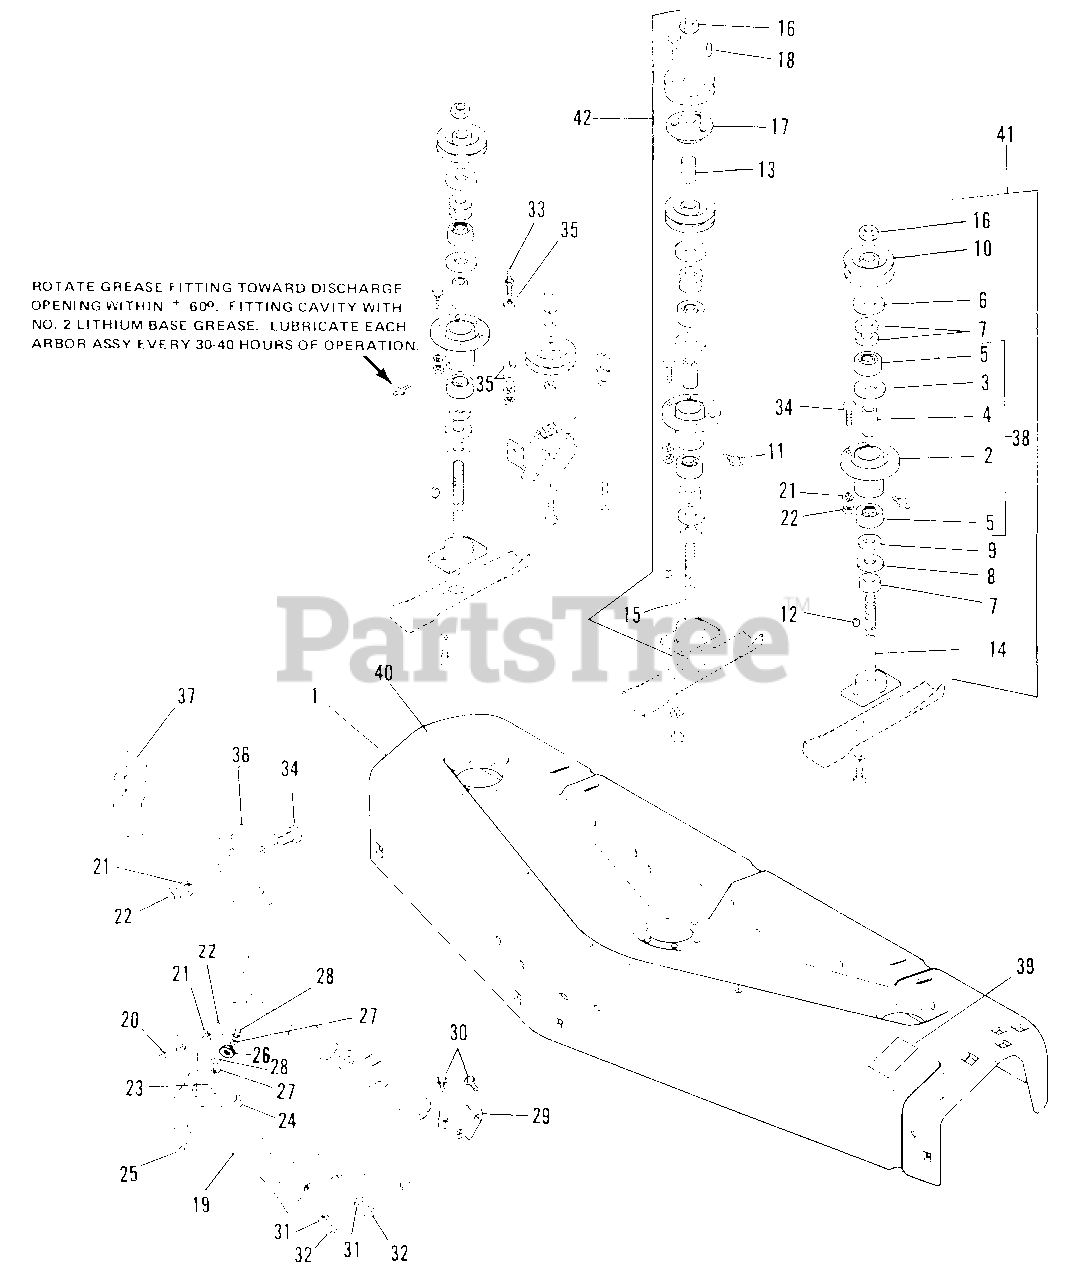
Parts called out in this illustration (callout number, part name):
1	HOUSING, 42"
2	TUBE ASSY
3	BACKING RING
11	FITTING, Grease
12	KEY, Woodruff, 3/16 x 5/8
14	ARBOR ASSY, Outer
15	ARBOR ASSY, Center
16	NUT, Full Hex Lock, 3/4-16
17	HUB, Pulley
20	CARRAIGE BOLT, 3/8-16 x 3/4
21	LOCKWASHER, 3/8
22	NUT, Hex Full, 3/8-16
23	CLIP, Baffle
24	SCREW, Self-Tapping, 1/4-20 x 7/8
25	CAPSCREW, Hex Hd., 1/4-20 x 5/8
26	WASHER, Plain, 1/4
27	LOCKWASHER, 1/4
28	NUT, Hex Full, 1/4-20
29	BRACKET, L.H. Roller
30	CARRIAGE BOLT., 5/16-18 x 3/4
31	LOCKWASHER, 5/16
32	NUT, Hex, 5/16-18
34	CAPSCREW, Hex Hd., 3/8-16 x 3/4
35	WASHER, Plain, 5/16
36	BRACKET, L.H.
37	BRACKET, R.H.
38	BEARING & TUBE ASSY
39	DECAL, Danger
40	DECAL, Caution
41	ARBOR KIT, Side
42	ARBOR KIT, Center
